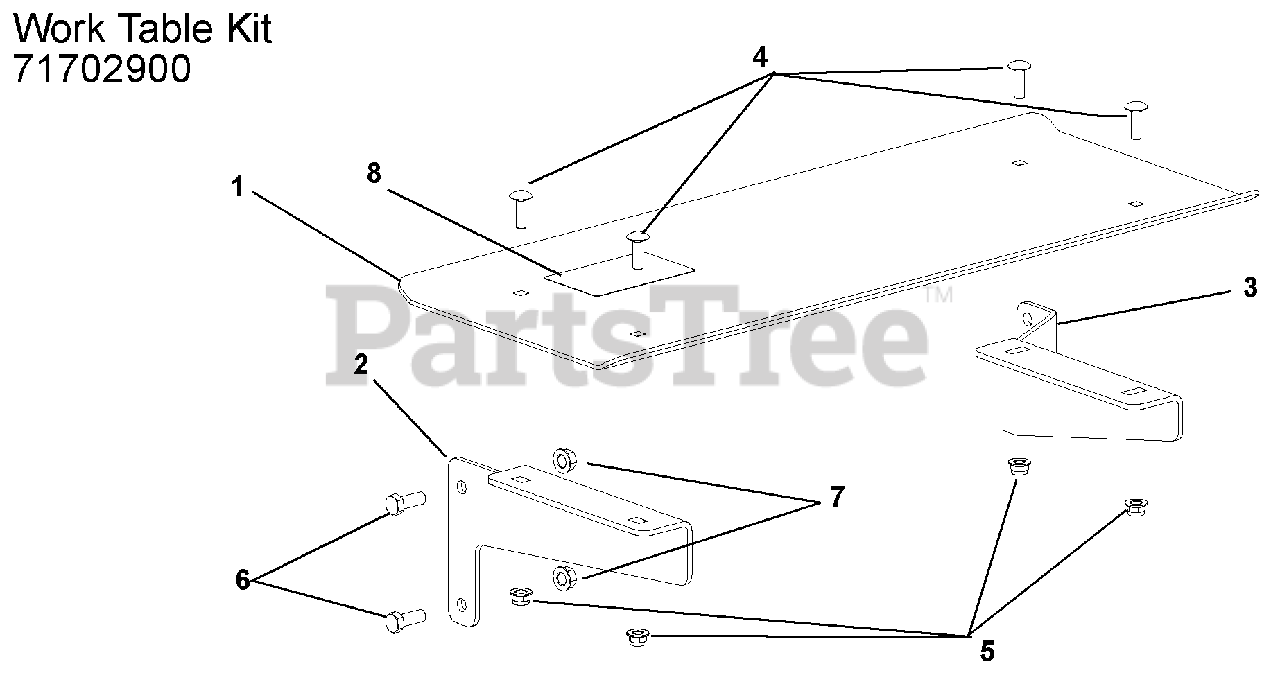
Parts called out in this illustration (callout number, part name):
1	TABLE, WORK - LOG SPLITTER
2	BRKT, FRONT - WORK TABLE
3	BRKT, REAR - WORK TABLE
4	@BLT-RHDSSQNK .31-18X1.00 G5YZ
5	@NUT-LK-NYL-FLG .31-18 YWZC
6	@BLT-HEX .38-16X1.00 GR5 YWZC
7	@NUT-LK-TOP-FLG .38-16 YWZC
8	DECAL,SPLITTER TABLE
